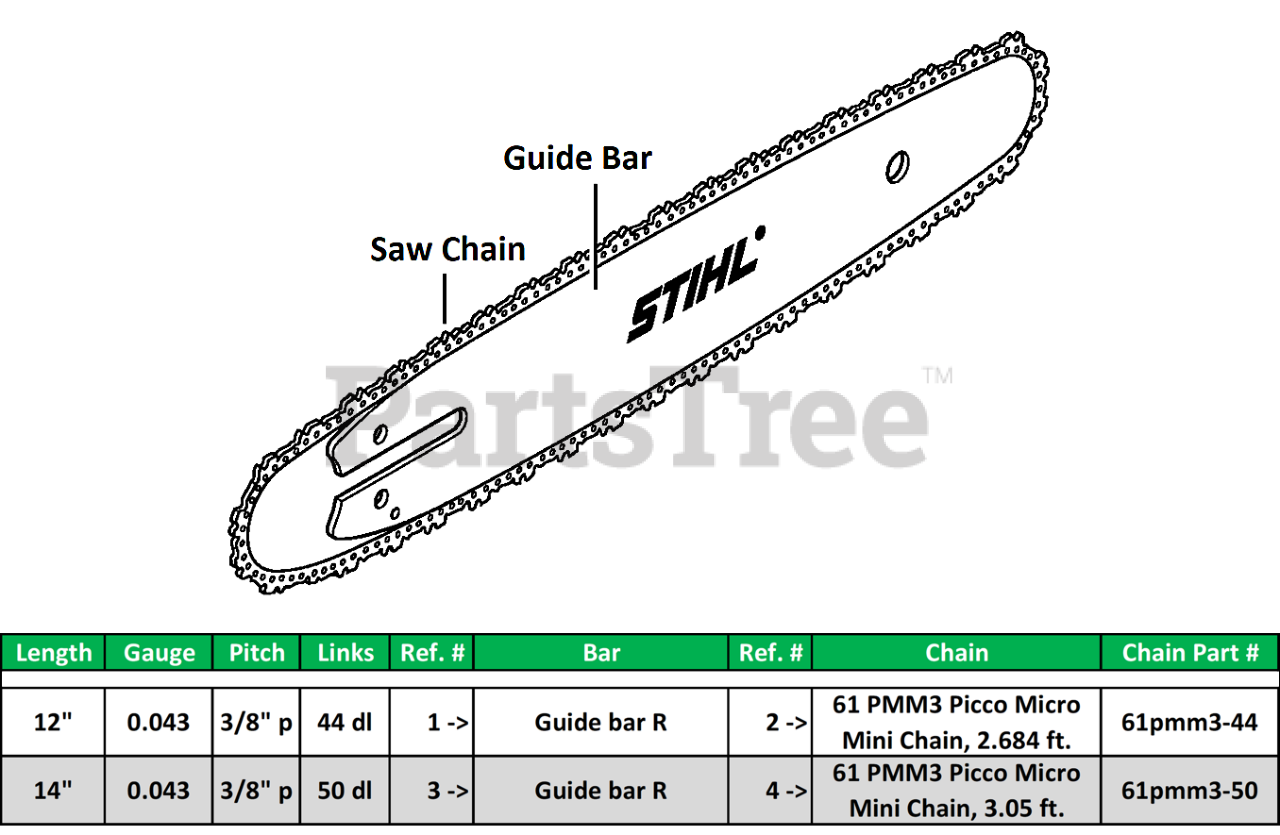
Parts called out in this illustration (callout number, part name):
1	Guide bar R 30cm/12" 1,1mm/0.043" 3/8" P
2	61 PMM3 Picco Micro Mini Chain, 2.684 ft.
3	Guide bar R 35cm/14" 1,1mm/0.043" 3/8" P
4	61 PMM3 Picco Micro Mini Chain, 3.05 ft.
